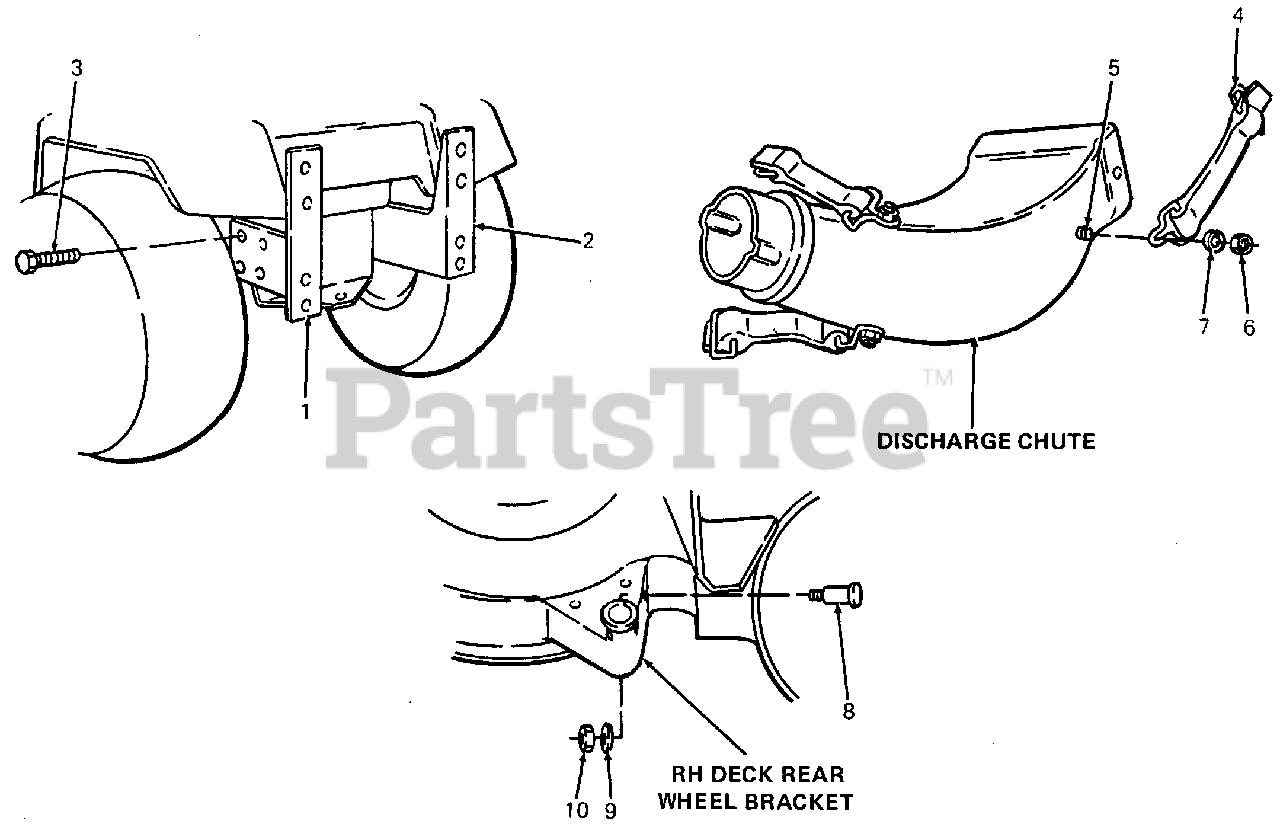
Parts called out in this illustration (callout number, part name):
1	Bracket, LH - Bagger Support
2	Bracket, RH - Bagger Support
3	Screw, Hex Cap, 3/8-16 X 1.0 Lg GR 5
4	Strap Assy, Retainer
5	Screw, Hex Cap, 1/4-20 X .62 Lg
6	Nut, Hex Insert Lock, 1/4-20
7	Washer, Spring, .265 ID X .562 OD
8	Screw, Shoulder
9	Washer, Bell
10	Nut, Hex Center Lock, 3/8-16
